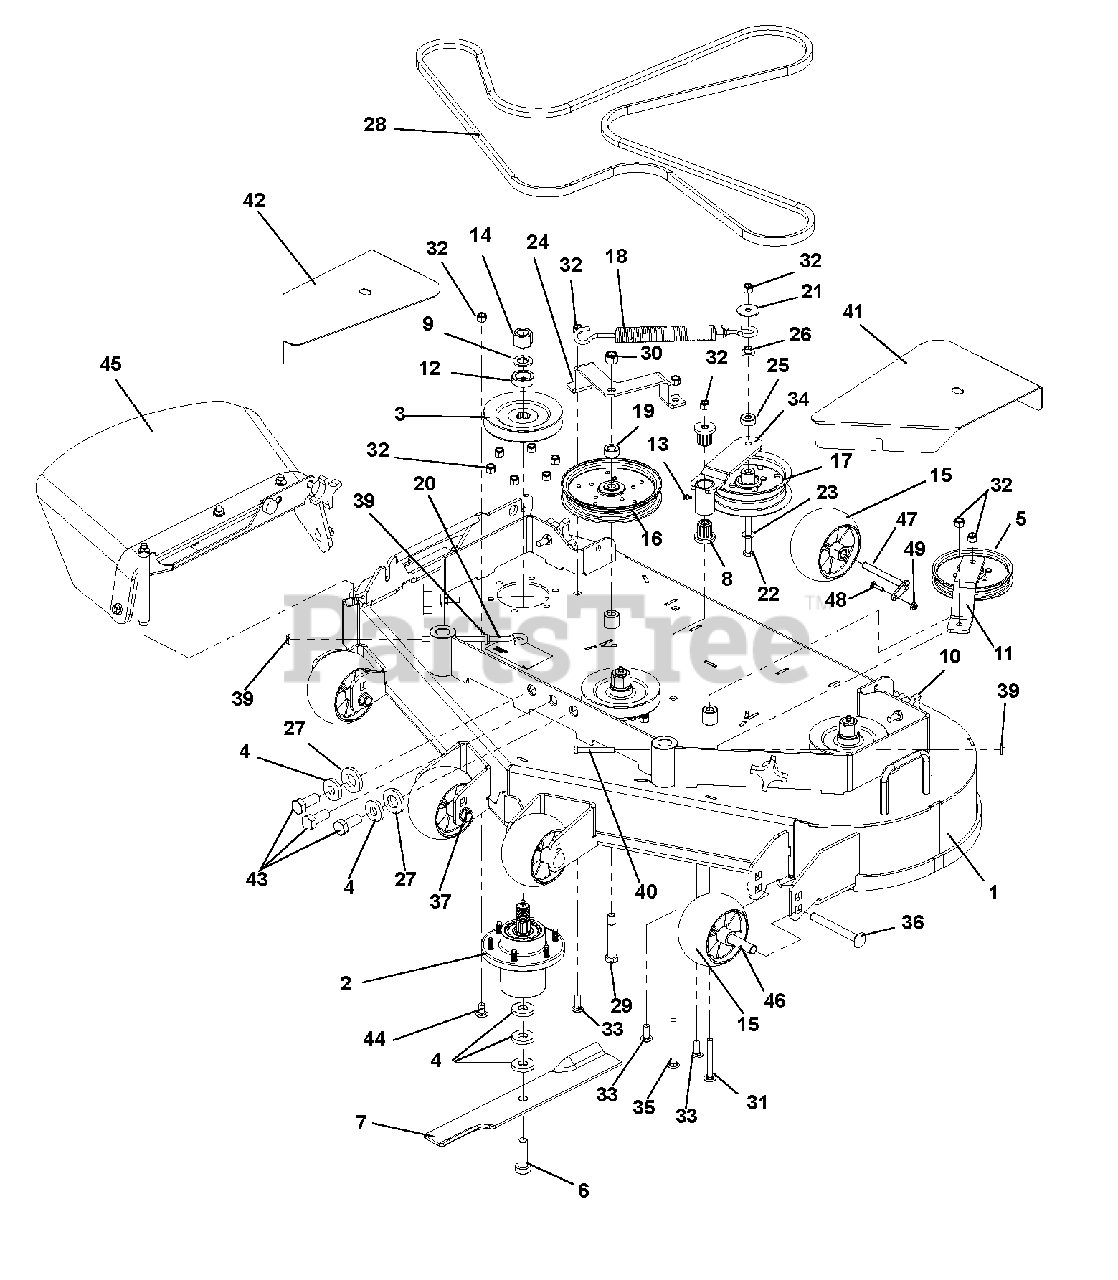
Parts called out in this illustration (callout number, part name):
1	48" Gravely Gear Deck with Decals
2	Assembly, Spindle S/O
3	Pulley, Spline Spindle SH (SN 000101 – 021000)
4	Washer, Flat-Steel .630 x 1.50 x .25
5	Pulley, Flat Idler
6	Bolt, Hex .62-11 x 2.00 Grade 8
7	Blade, 16.500 Lo-Lift
8	Bearing, Flange M10 x M25 x M27 Fluted
9	Washer, .75 x 1.3125 x .120
10	Knob, .375 x 1.25-4 Prong (SN 000101 – 019999)
11	Strap, Idler 48/52 WALK
12	Spacer, 1.500 x 1.000 x .510 (SN 000101 – 020999)
13	Fitting, .25-28 STRGT Grease Zerk
14	Locknut, .75-16 Crown Grade 5
15	Anti-Scalp Wheel- 5X3 Center
16	Idler, Flat-Pulley 6.75 x .510
17	Pulley, Flat 5.00 x .375 w/BRG
18	Spring, Extension
19	Bushing, Spacer .502 x .997 x .50
20	Bolt, Eye .31-18X5.50 .62 Diameter
21	Washer, Flat-Steel .38 x 1.50 x .062
22	Bolt, Hex .38-16 x 3.00 Grade 5
23	Washer, Flat-Steel .406 x .812 x .065
24	Bracket, Idler Support
25	Bushing, .380 x 1.00 x .410
26	Bushing-Flange .385 x .500 x .875 x .406
27	Washer, .905 x 1.750 x .250
28	V-Belt, B-Wrapped
29	Bolt, Hex .50-13 x 3.25 Grade 5
30	Nut, Locking-Nylon .50-13
31	Bolt, Round Head Square Neck .38-16 x 3.00 Grade 5
32	Nut, Locking-Nylon .38-16
33	Bolt, .38-16 x 1.00 Round Head Square Neck Grade 5
34	Weldment, Idler Arm w/Offset
35	Bolt, .38-16 x 3.50 Round Head Square Neck Grade 5
36	Bolt, .50-13 x 4.50 Round Head Square Neck Grade 5
37	Nut, Locking-Nylon-Flange .50-13
38	Bolt, .25-20 x 1.00 Round Head Square Neck Grade 5 (SN 000101 – 020999)
39	Nut, Spin Lock-Flange .312-18
40	Bolt, 5/16-18 x 2.50 Hex 8
41	Guard, LH 48" Belt
42	Guard, RH 48" Belt
43	Bolt, Hex .62-11 1.5 Grade 8
44	Bolt, .38-16 x .75 Round Head Square Neck Grade 5
45	Discharge Shield Assembly (see page 23 for individual parts)
46	Spacer, .510 x .625 x 3.25
47	Pivot, Retainer Weldment
48	Bolt, Round Head Square Neck .25-20 x 1.00 Grade 5
49	Nut, Locking-Nylon .250-20
